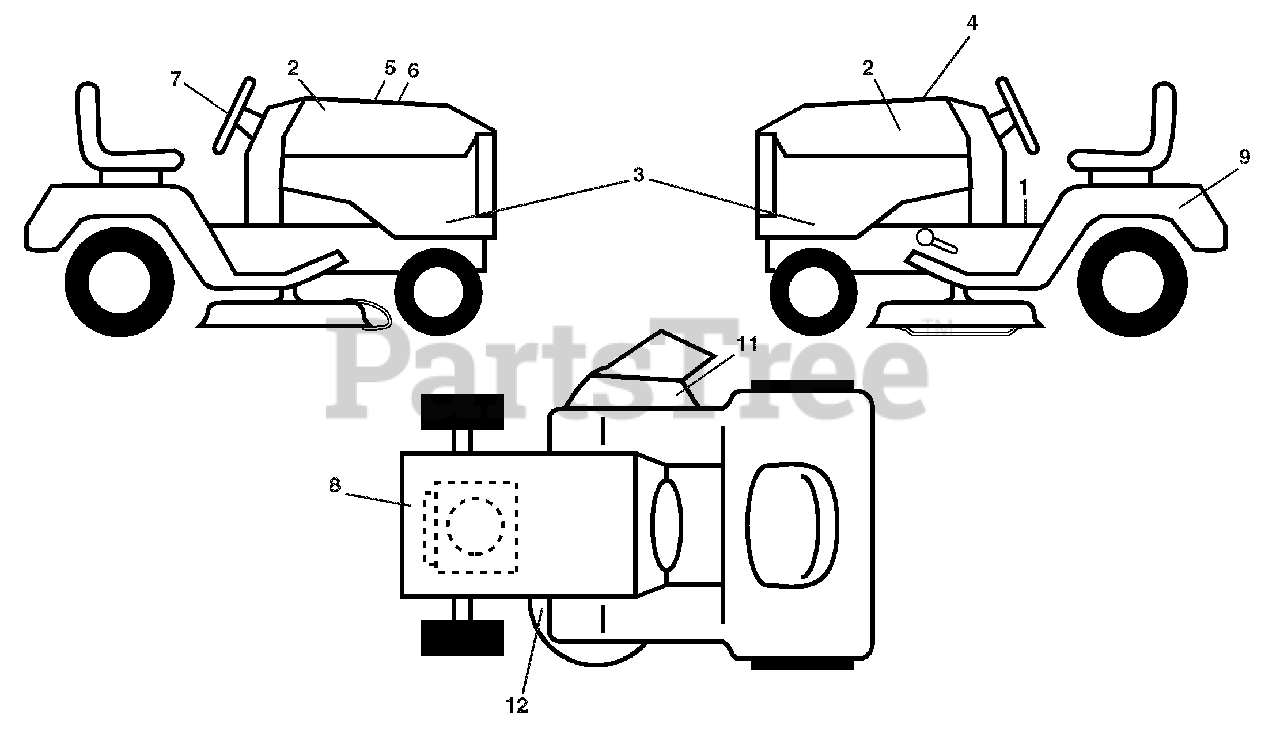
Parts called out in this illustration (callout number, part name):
1	Decal, Operators
2	Decal, Hood
3	Decal, Hood Panel SD
4	Decal, Hood Top Insert
5	Decal, Customer Respons.
6	Decal, Replacement
7	Decal, Steering Wheel
8	Decal, Eng. HP
9	Decal, Battery Dnge/Poi
11	Decal, Warning
12	Decal, Mower V-Belt Schematic
12	Decal, Bypass
12	Pad, Footrest, LH
12	Pad, Footrest, RH
12	Manual, Owner's
